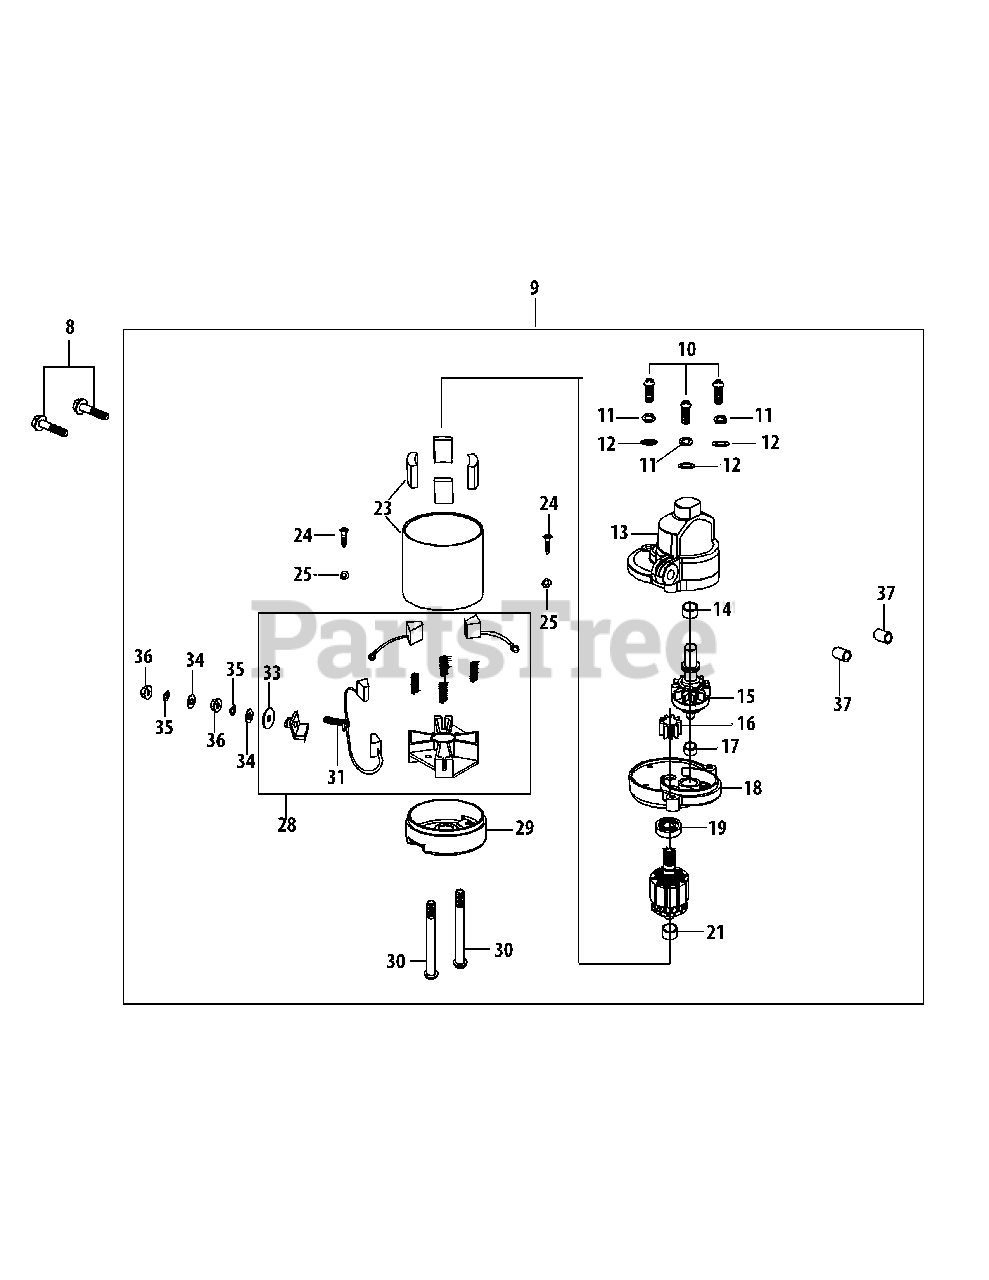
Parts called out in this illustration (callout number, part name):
8	Bolt M8×40
9	Starter Assembly
10	Screw M5×25
11	Lock Washer 5
12	Plain Washer 6
13	Electrical Starter Front Cover
14	Bearing
15	Pinion/Clutch Assembly
17	Bearing
18	Pinion Cover
19	Bearing
21	Bearing
23	Starter Housing Assembly
25	Lock Washer
28	Brush Assembly
29	Electrical Starter Back Cover
30	Bolt M6×100
31	Bolt M6×30 Assembly
33	Insulation Washer
34	Plain Washer 6
35	Lock Washer 6
36	Nut M6
37	Dowel Pin 10×14
